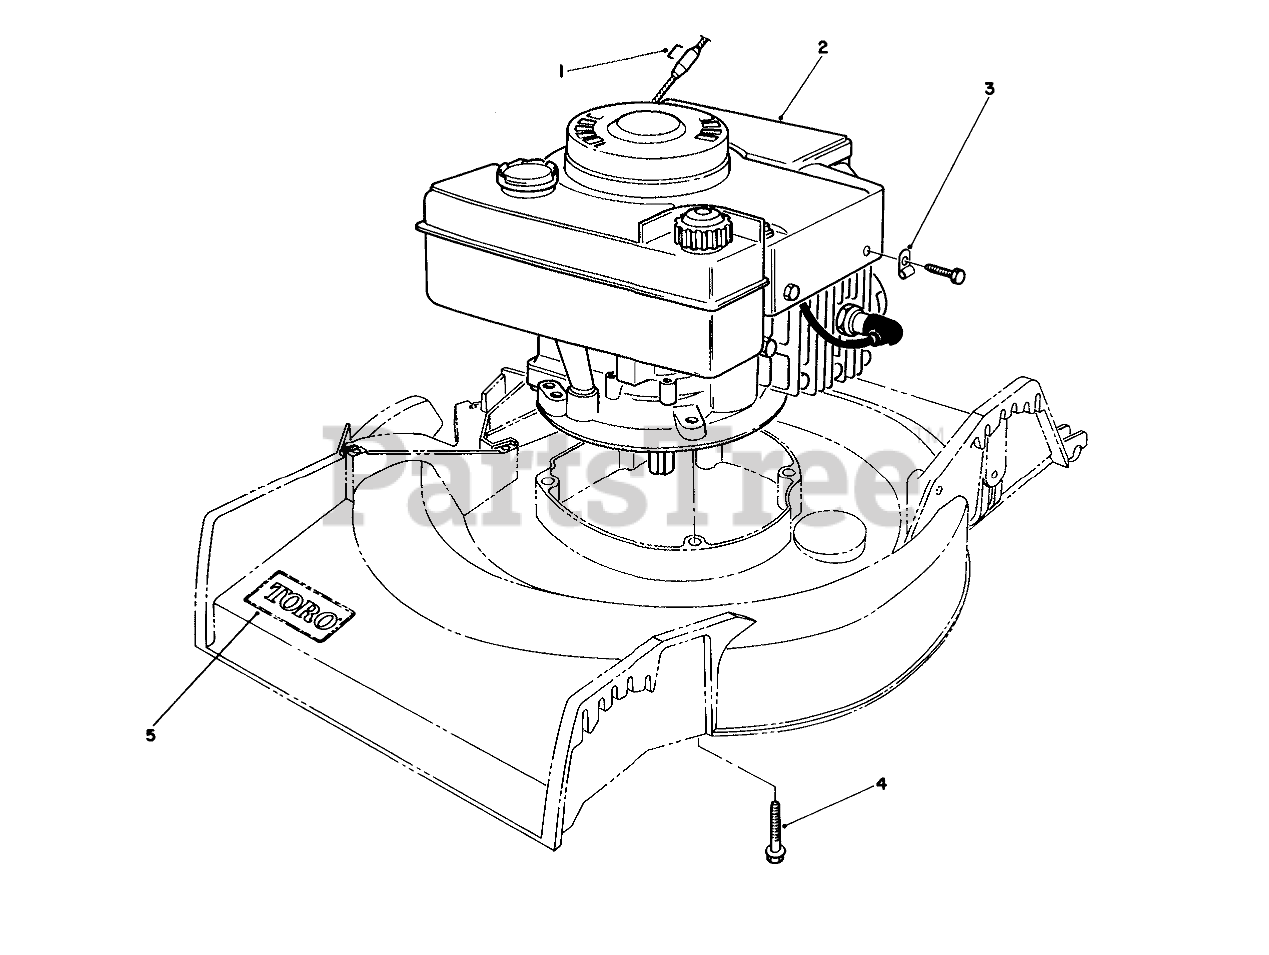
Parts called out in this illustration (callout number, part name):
1	Staple
3	CLAMP
4	3/8-16 X 2-3/4 CAPSCR
5	DECAL
